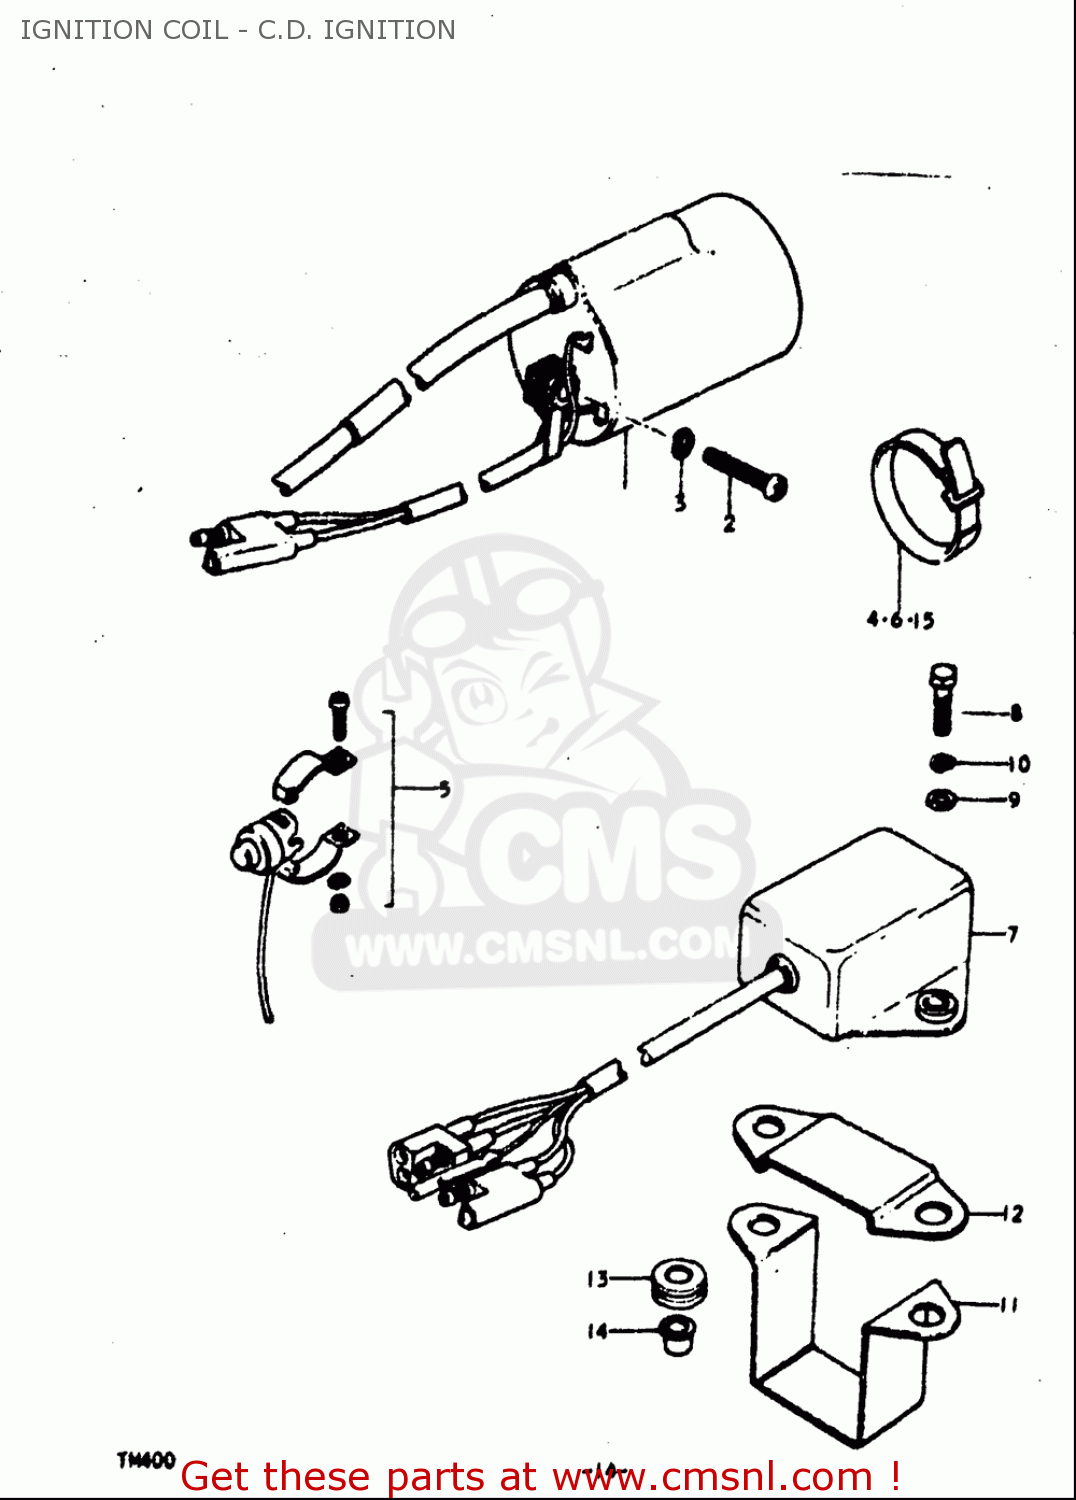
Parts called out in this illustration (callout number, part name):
2	SCREW
3	WASHER,LOCK
4	CLAMP(L:120)
5	SWITCH ASSY,ENGINE STOP
8	BOLT
9	WASHER
10	WASHER,LOCK
13	CUSHION
15	CLAMP
